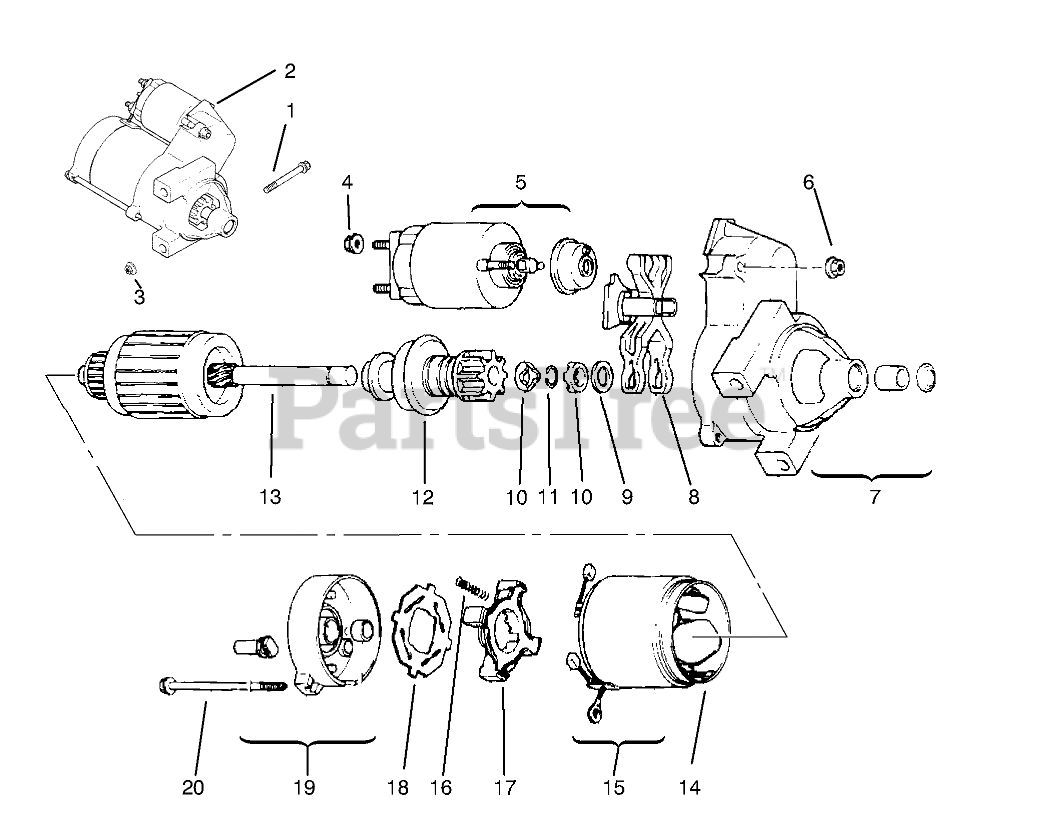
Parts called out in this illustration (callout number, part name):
2	Starter INC 4-20
4	Nut
5	Solenoid
6	Nut
7	Cap Drive End
8	Lever Starter Drive
9	Washer-Thrust
10	Nut
11	Ring-Retainer
12	Drive Pinion
13	Armature
14	Frame
15	Brush Kit
16	Spring Brush
17	Holder-Brush
18	Insulator
19	Cap-Commutator End
20	Bolt
